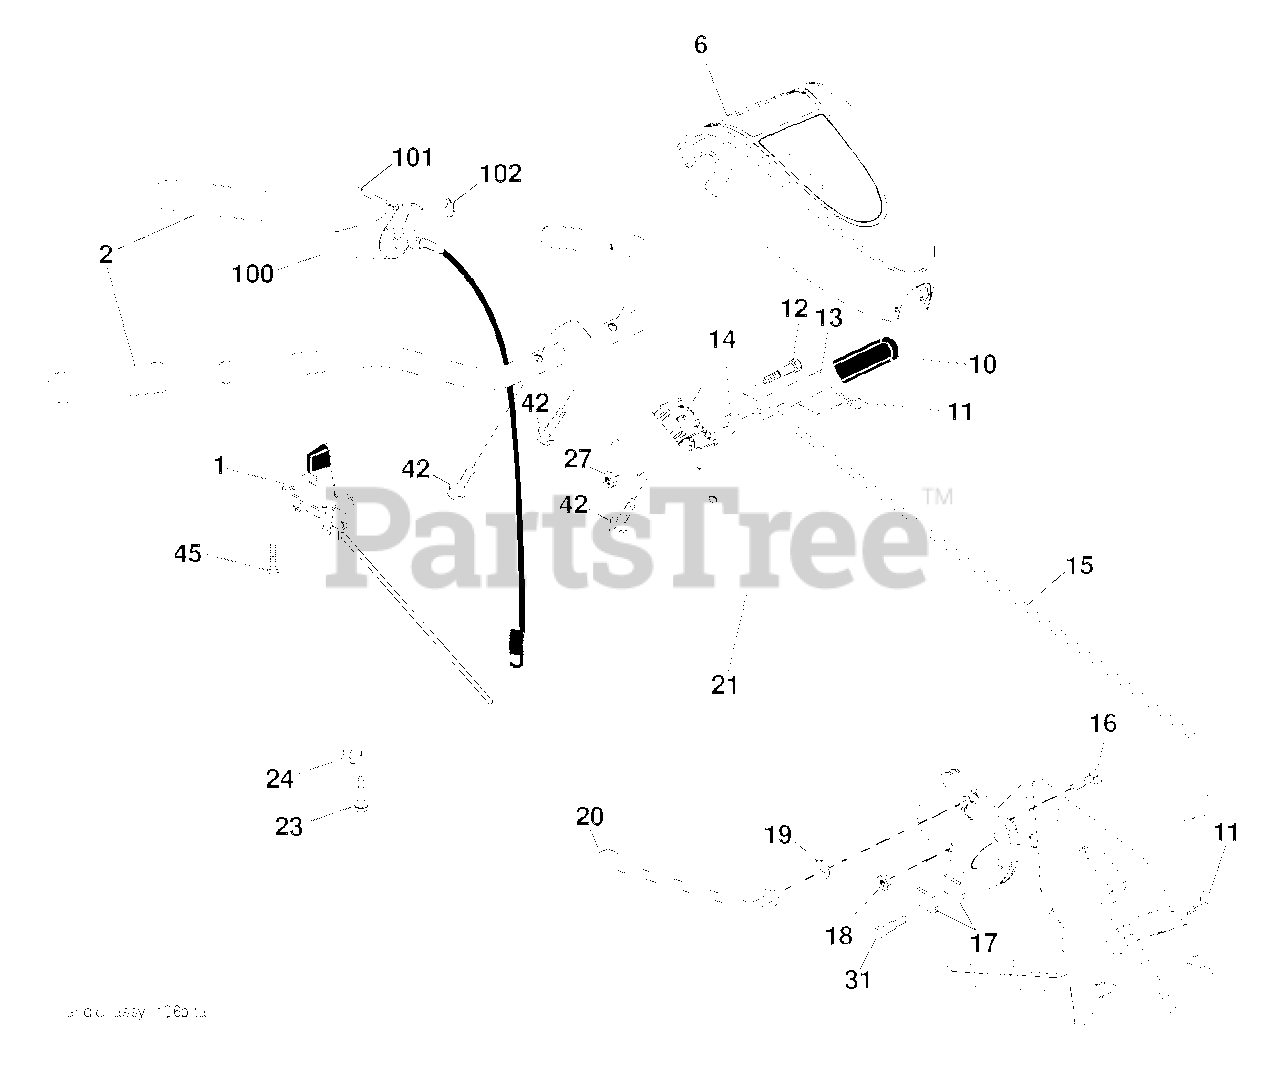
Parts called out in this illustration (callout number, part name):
1	THROTTLE.CONTROL.RT.INTEK.50
2	GRIP.1X5.06
6	CONSOLE.GREY.DRT.W.S.DRT900E
10	GRIP T
11	RETAINER M
12	SHOULDER BOLT ST
13	HANDLE
14	GROMMET.RUBBER.CRT.TILLER
15	ROD.SHIFT.YARD PRO.UNIVERSAL.
16	BOLT D
17	LOCK.HANDLE.CRT
19	WASHER CRT
20	LEVER.LOCK.CRT
21	HANDLE.ASM.HUSQ/P.PRO.GREY
23	TAPPING SCREW
24	CLIP.PLATED
27	NUT T
31	BOLT.PIVOT
42	SCREW.#10 X 0.750.BOS
45	SCREW.#10 X 0.500
100	CONTROL.ASSEMBLY.TINE.TILLER
101	PIN, PIVOT
102	RETAINING.RING.#5103-25
